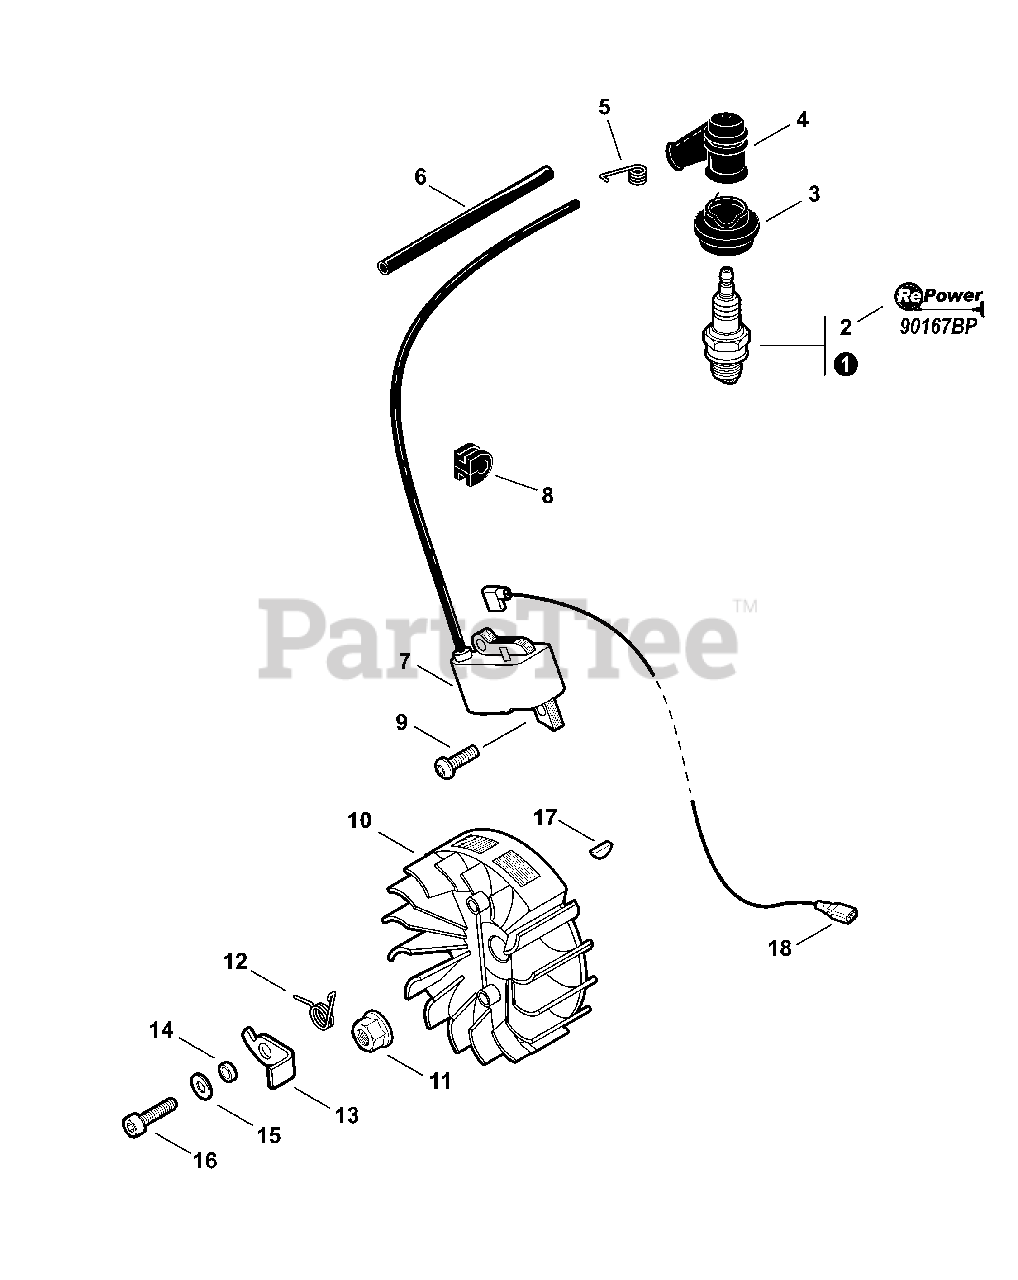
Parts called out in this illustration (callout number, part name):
1	PLUG, SPARK (BPM-8Y)
2	PLUG, SPARK (BPMR-8Y)
3	COVER,CAP
4	CAP,SPARK PLUG
5	TERMINAL,SPARKPLUG
7	COIL, IGNITION
9	BOLT, TORX 5
10	ROTOR, MAGNETO
11	NUT, FLANGE 8
12	SPRING, RETURN
13	PAWL, STARTER
14	SPACER, RATCHET
15	WASHER 5
16	BOLT, TORX 5
17	KEY, WOODRUFF
